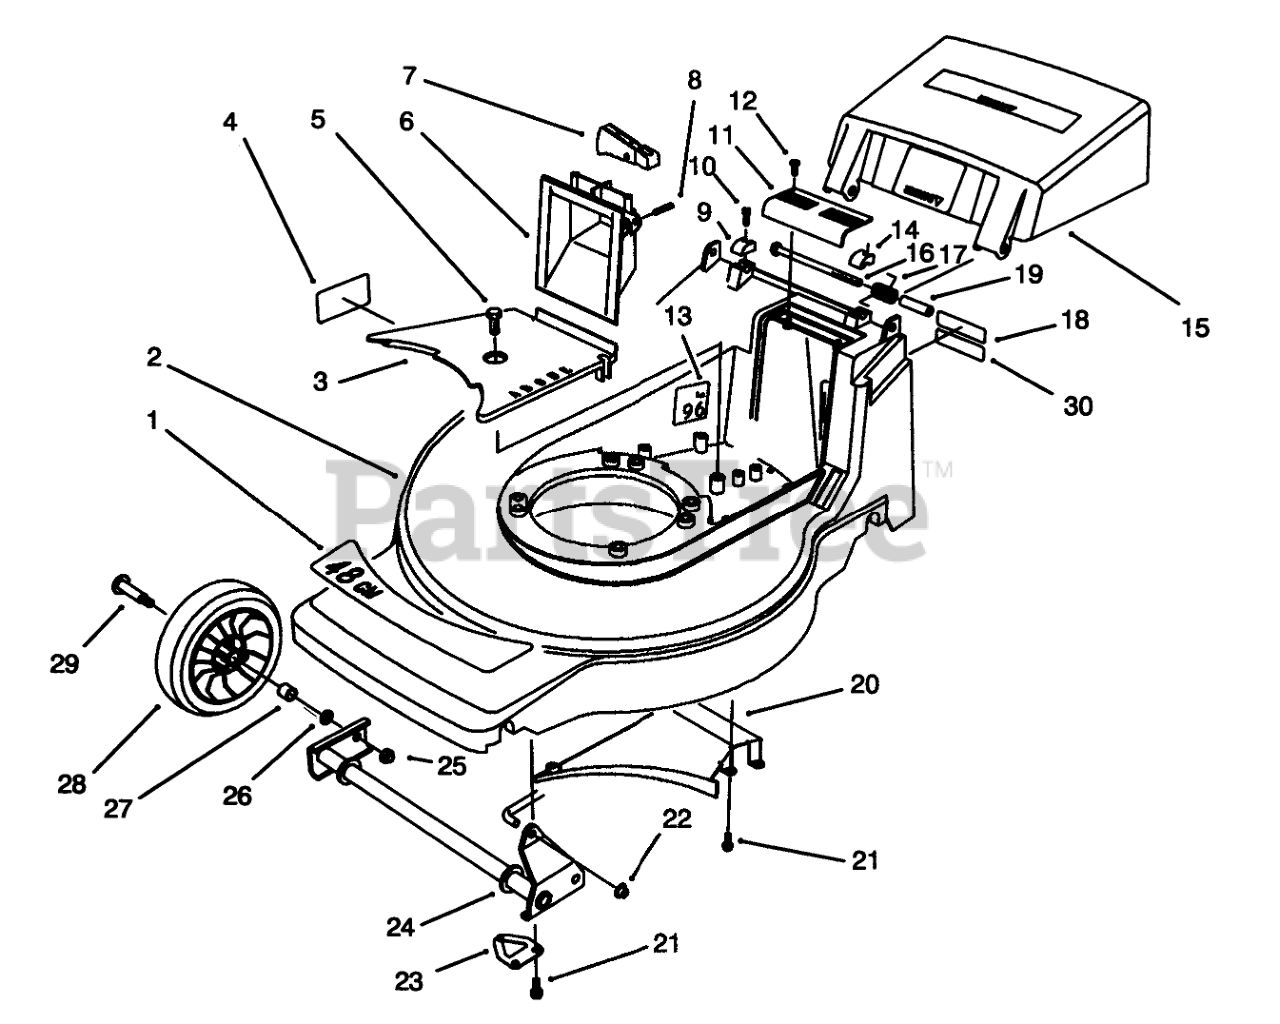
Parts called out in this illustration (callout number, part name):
1	DECAL - DECK 48 CM
2	Housing-48cm (Incl. Ref. #4)
3	BELT COVER
4	Decal Danger
5	SCREW-HWHTF
6	GRIP - LOWER
7	TRIGGER - HOC
8	PIN-SPIRAL
9	CAP-HINGE BOLT, RH
10	SCREW-HSH
11	GRIP-UPPER
12	SCREW-PPH, PLASTITE
13	Decal-Noise Rating
14	CAP-HINGE BOLT, LH
15	HP DISCHARGE DOOR
16	SCREW-HH
17	SPRING-DOOR
18	DECAL FRENCH REGUL.
19	SPACER-DOOR
20	Ramp-Discharge
21	SCREW-HWH
22	NUT-PUSH
23	SHAFT RETAINER ASM
24	FRONT PIVOT WA
25	NUT-HEX
26	WASHER
27	BUSHING
28	Wheel & Tire Assembly (Incl. Ref. #27)
29	BOLT-WHEEL
30	Decal-Power Rating
